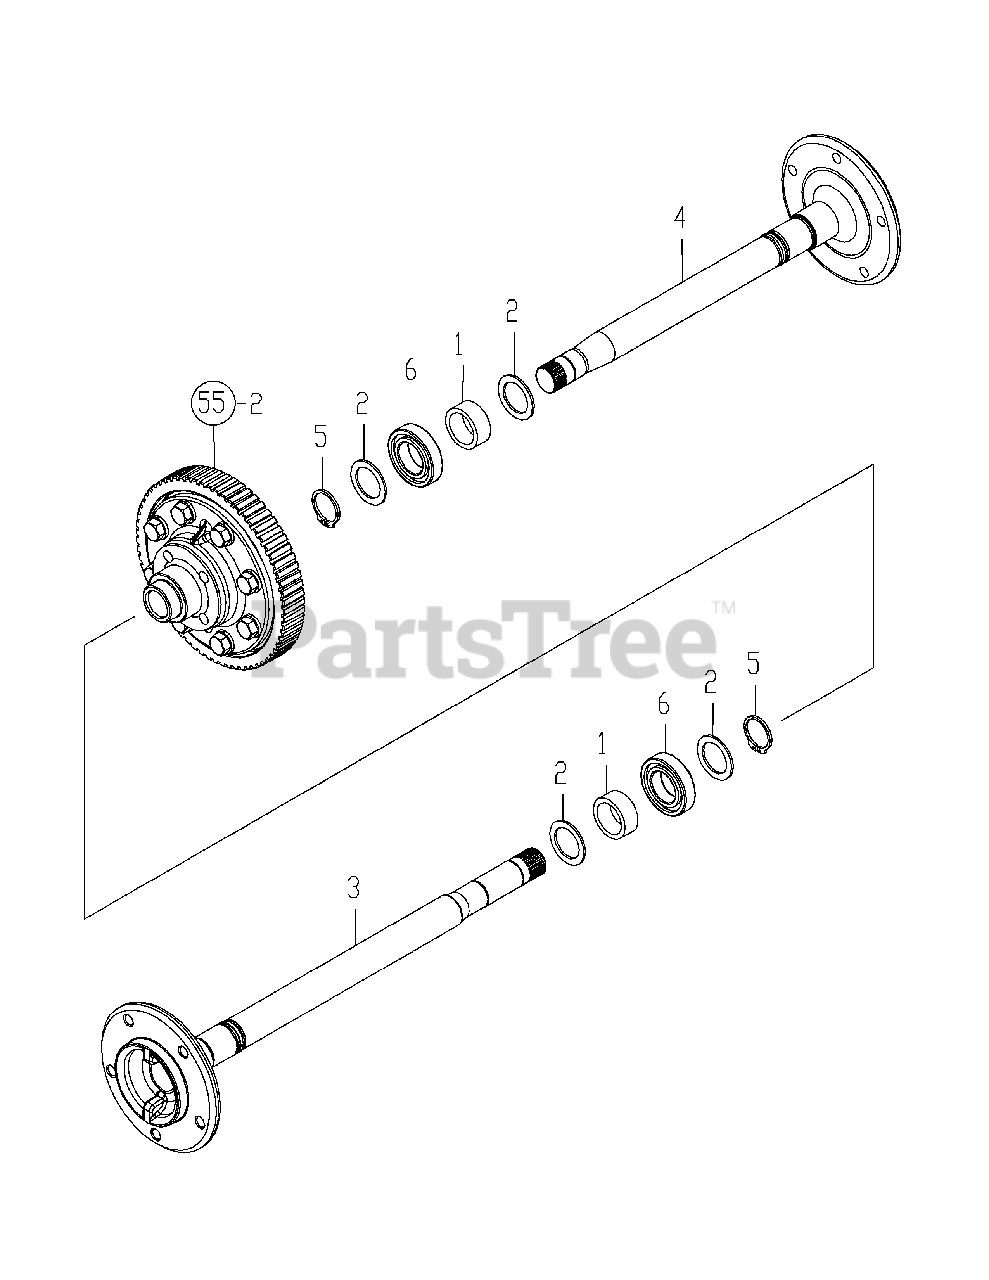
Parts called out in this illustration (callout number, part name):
1	SLEEVE, 30X39X16
2	COLLAR, 30X42X2
3	SHAFT, REAR AXLE L
4	SHAFT, REAR AXLE R
6	BEARING, 6006 NTN
